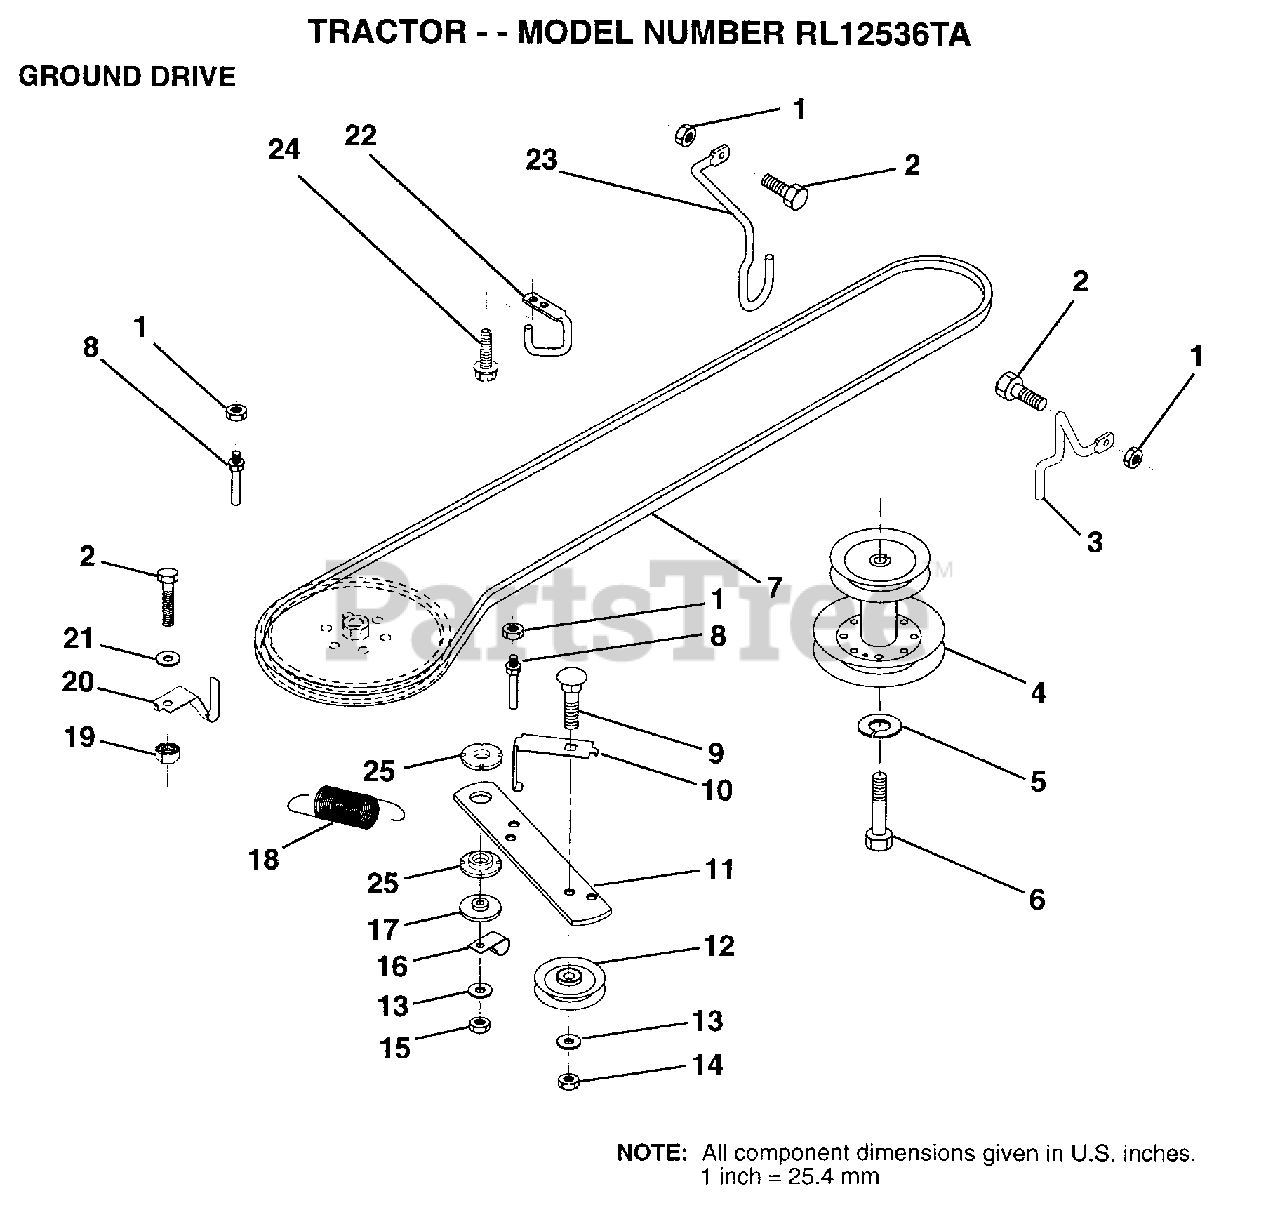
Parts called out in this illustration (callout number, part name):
2	BOLT
3	KEEPER RH
4	PULLEY.ENGINE.LR
5	LOCKWASHER
6	HEX BOLT
7	BELT
8	"KEEPER,DRIVE BELT"
9	BOLT
10	"KEEP,IDLER DR BEL"
11	ARM-IDLER.DR.GRND
12	PULLEY.IDLER.FLAT
13	WASHER
14	LOCKNUT
16	"CLIP,INSULATOR"
17	SPACER
20	KEEPER.BELT.T/A
21	WASHER
22	"KEEPER,FRA DR BEL"
23	KEEPER MOWER LH
24	SCREW
25	BUSHING.NYLON
